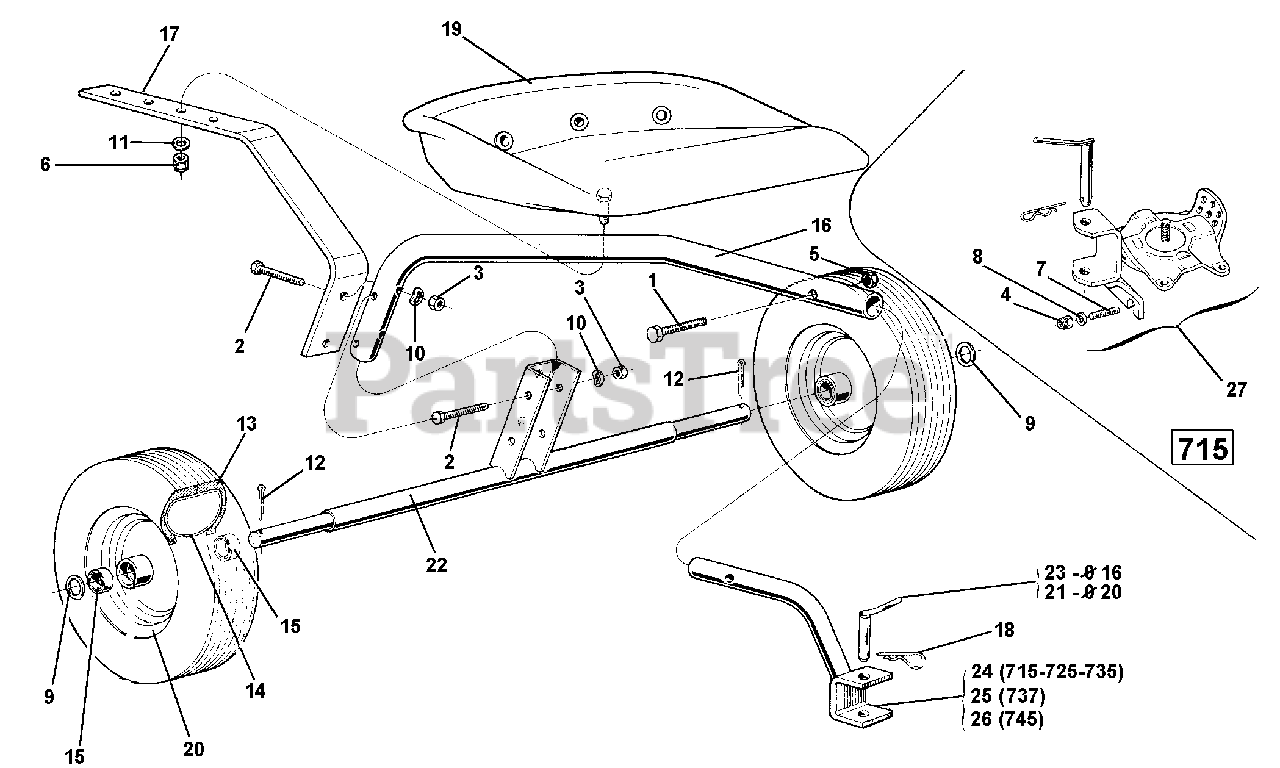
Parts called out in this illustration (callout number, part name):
1	SCREW M10 X 60
2	SCREW TE M10 X 65 UNI 5739-8G
4	NUT, SELF LOCKING M8
5	NUT, SELF LOCKING M10
6	NUT, SELF LOCKING M12
7	STUD M8 X 38 X 14 X 20
8	WASHER, FLAT 8.4
9	WASHER, FLAT 26
10	WASHER, LOCK 10.5
11	WASHER, LOCK 13
12	PIN, COTTER A 5 X 40 UNI 1336
13	TIRE FOR CAR 100 X 203
14	TUBE 4.00 X 8
17	SEAT SPRING
19	PADDED SEAT
20	SULKY WHEEL
24	CURVED COUPLING 725-735
25	CURVED COUPLING 737
26	CURVED COUPLING 745
27	TOW COUPLING 715
